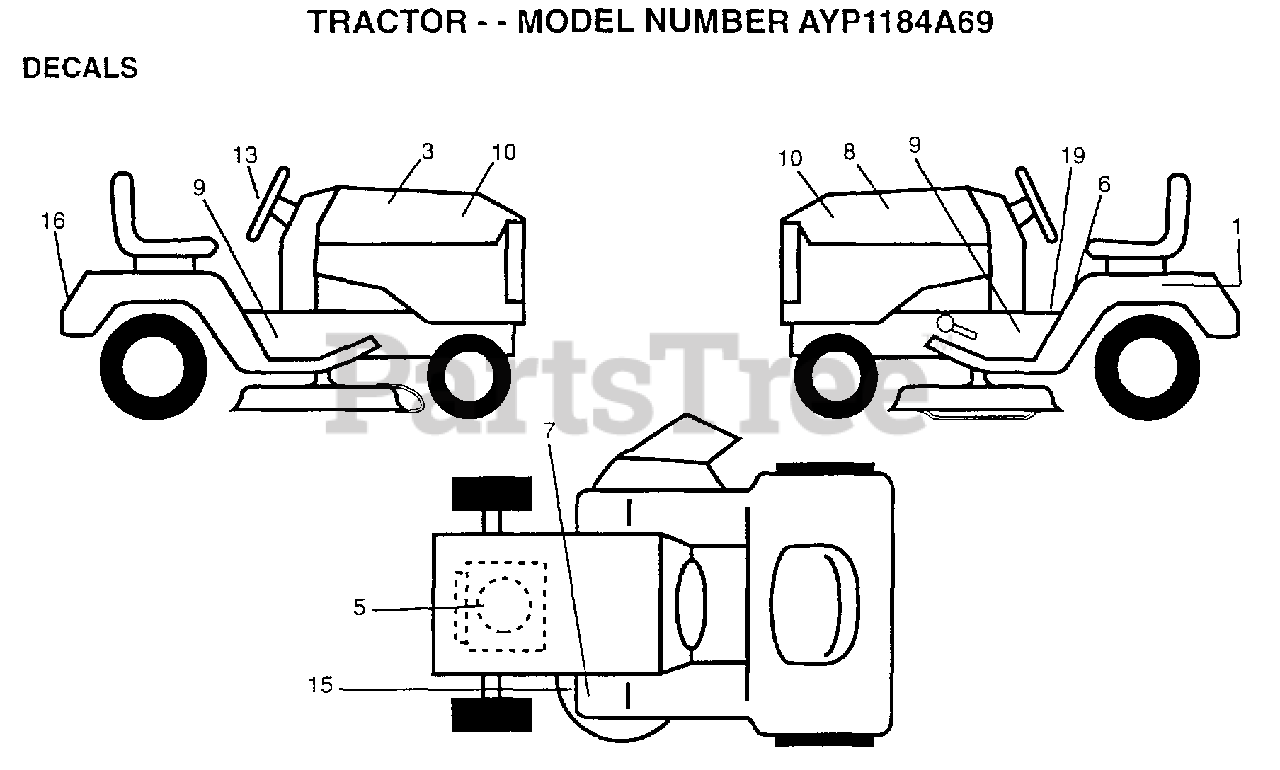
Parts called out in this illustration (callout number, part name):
1	DECAL.BTRY.DANGER
3	DECAL.HD.RH.WIZAR
5	DECAL ENGINE
6	DECAL
8	DECAL.HD.LH.WIZAR
9	DECAL CHASSIS WIZ
10	DECAL.INS.HD.WIZA
13	DECAL.INS.STRG.WL
15	DECAL
